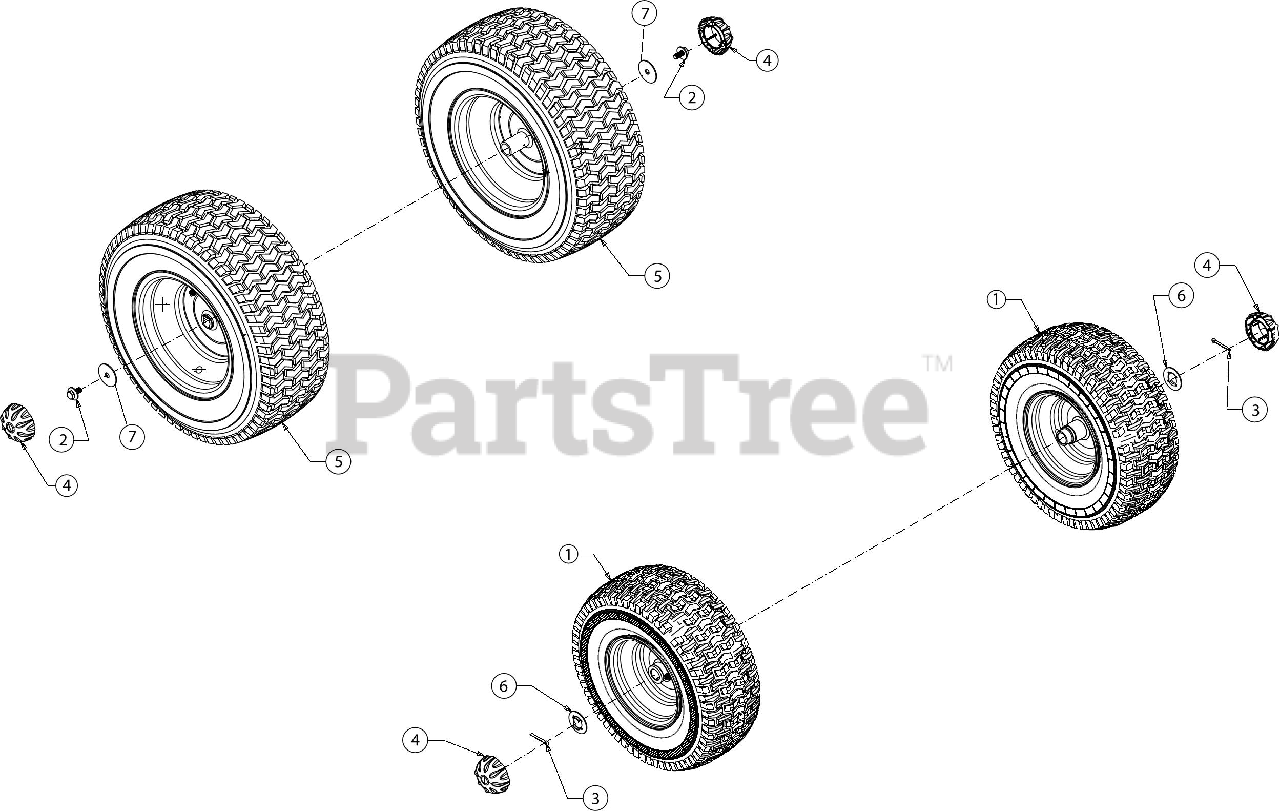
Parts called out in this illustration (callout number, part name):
2	SCREW 5/16-24 x .750 GR5
3	COTTER PIN-5/32 DIA
4	HUB CAP
6	FLAT WASHER .781 ID x1.590 OD
7	FLAT WASHER .350X1.59X.062
